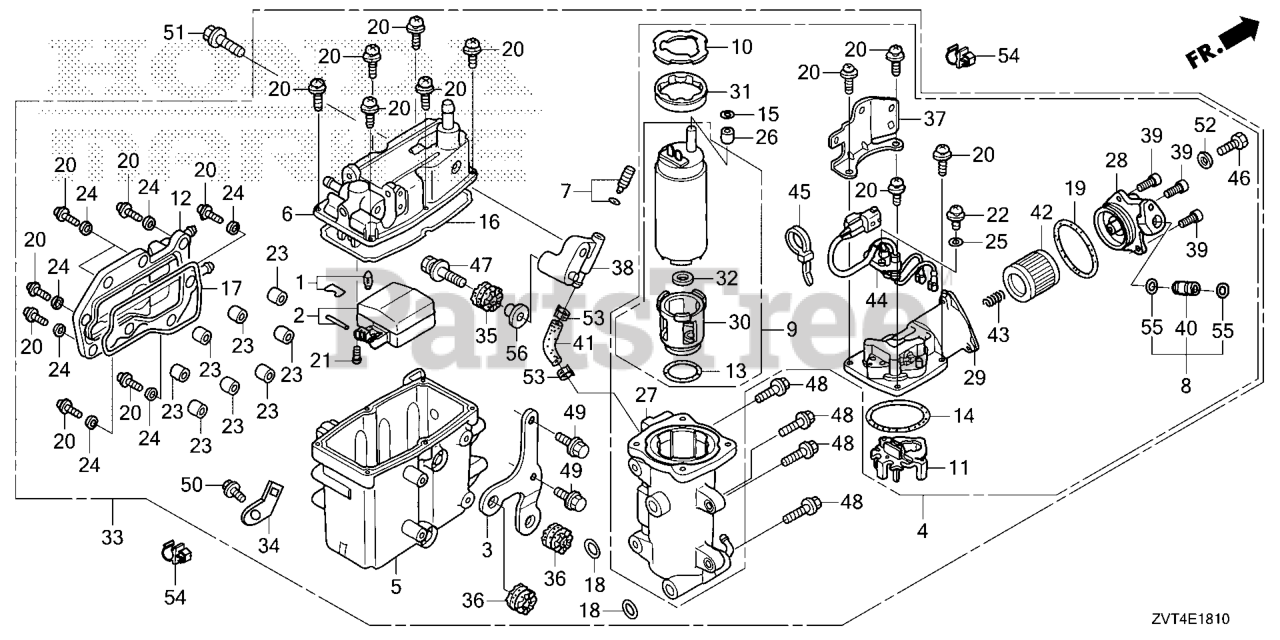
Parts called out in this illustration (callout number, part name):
1	VALVE SET, FLOAT
3	STAY A, PLATE
4	PUMP UNIT SET
5	BODY COMP, CHAMBER
6	COVER COMP
7	SCREW SET, DRAIN (CARBURETOR NO.)
9	PUMP UNIT, FUEL (B) (MSDS)
12	COVER, WATER JACKET
15	O-RING (7.3X2.2) (NOK)
20	SCREW-WASHER
21	SCREW, PAN
22	SCREW, WASHER
23	COLLAR, SET
24	WASHER, PLAIN
25	WASHER, PLAIN
27	CASE, PUMP
28	COVER B, PUMP
29	COVER, PUMP (A)
33	VAPOR SEPARATOR
34	STAY, FUEL PIPE
35	GROMMET, VAPOR SEPARATOR
36	GROMMET, VAPOR SEPARATOR
37	STAY, PLATE
38	STAY, VAPOR SEPARATOR
39	SOCKET BOLT
40	JOINT, FUEL PIPE
41	TUBE F, FUEL
42	SCREEN, FUEL STRAINER
43	SPRING, SET
46	BOLT, SEALING (6MM)
47	BOLT-WASHER (8X35)
48	BOLT, FLANGE (6X25)
49	BOLT, FLANGE (6X16)
50	BOLT, FLANGE (6X14)
51	BOLT, FLANGE (8X30)
52	WASHER, SEALING (6MM)
53	CLAMP, TUBE (8.0)
54	CLAMP, WIRE (8MM)
55	O-RING (7.8X1.9) (ARAI)
56	COLLAR (8.5X14.5)
